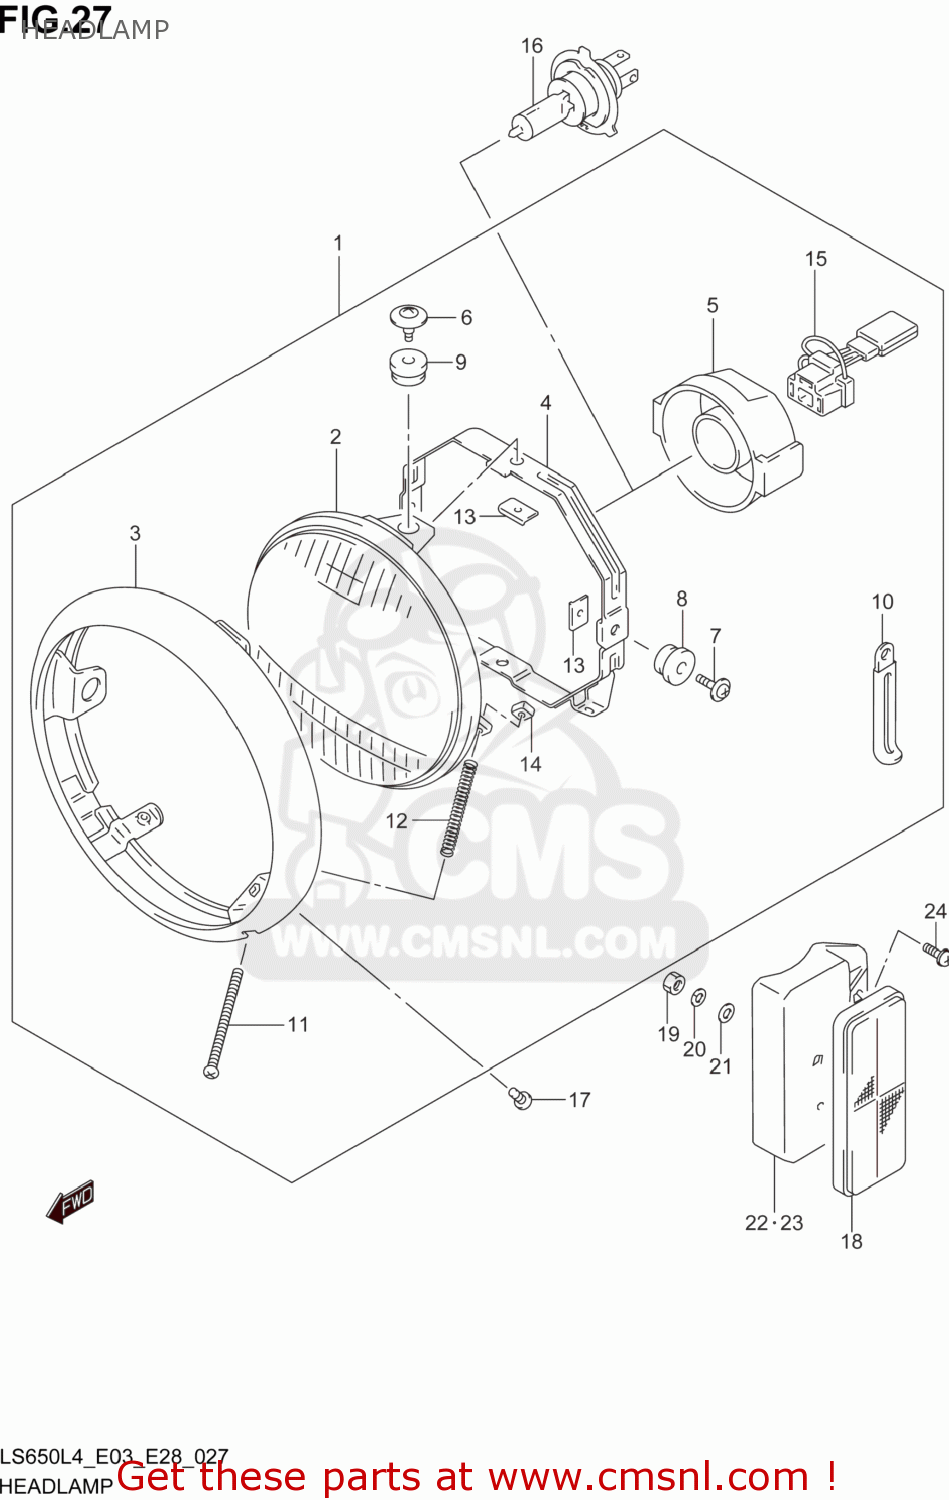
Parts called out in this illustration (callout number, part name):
1	HEADLAMP ASSY
2	UNIT,LAMP
3	RIM
4	RING,MOUNTING
5	COVER
6	SCREW
7	SCREW,MOUNTING
8	CUSHION
9	CUSHION
10	CLAMP(L:65)
11	SCREW,ADJUSTING(4X50)
12	SPRING
13	NUT
14	NUT,HEADLAMP ADJUST
15	SOCKET
16	BULB(12V60/55W,H4)
17	SCREW
18	REFLEX REFLECTOR,FR SIDE
19	NUT
20	WASHER,LOCK
21	WASHER(5.5X16X1.2)
22	BRACKET,FR SIDE RR,R
23	BRACKET,FR SIDE RR,L
24	SCREW(5X12)
